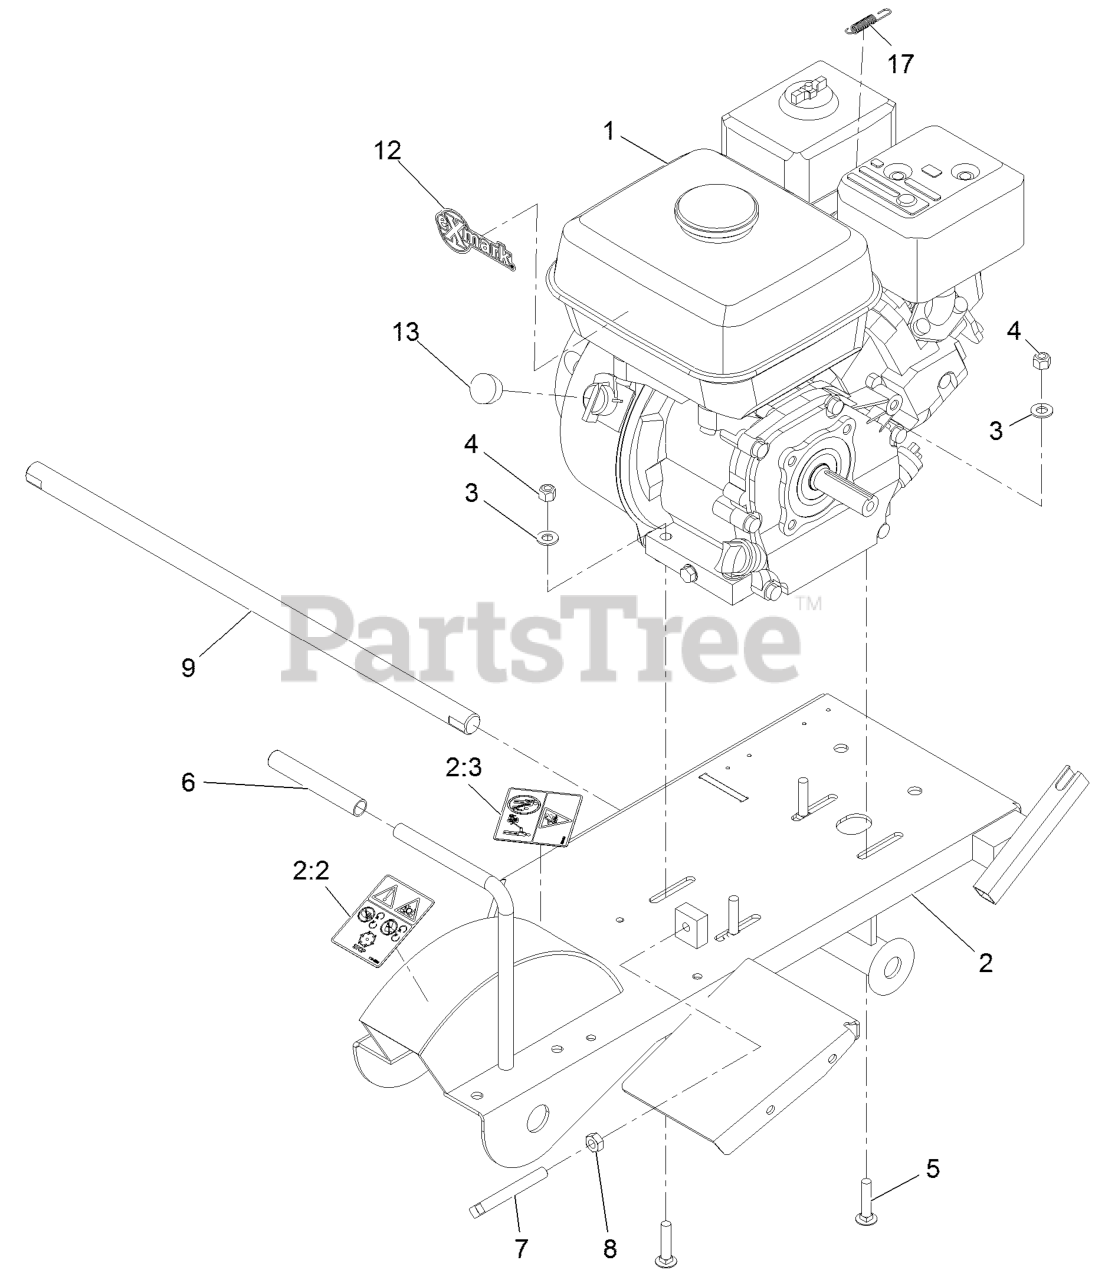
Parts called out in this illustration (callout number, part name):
2	Frame Asm,
2:2	DECAL-DANGER
2:3	DECAL-CAUTION
3	WASHER-FLAT
4	NUT-LOCK, NI
5	BOLT-CARR
6	GRIP-RUBBER
7	SCREW-SET, SQH
8	NUT-HEX
9	BAR-AXLE, WHEEL
12	DECAL,EXMARK
13	PLUG-ENGINE
17	SPRING-EXTENSION
